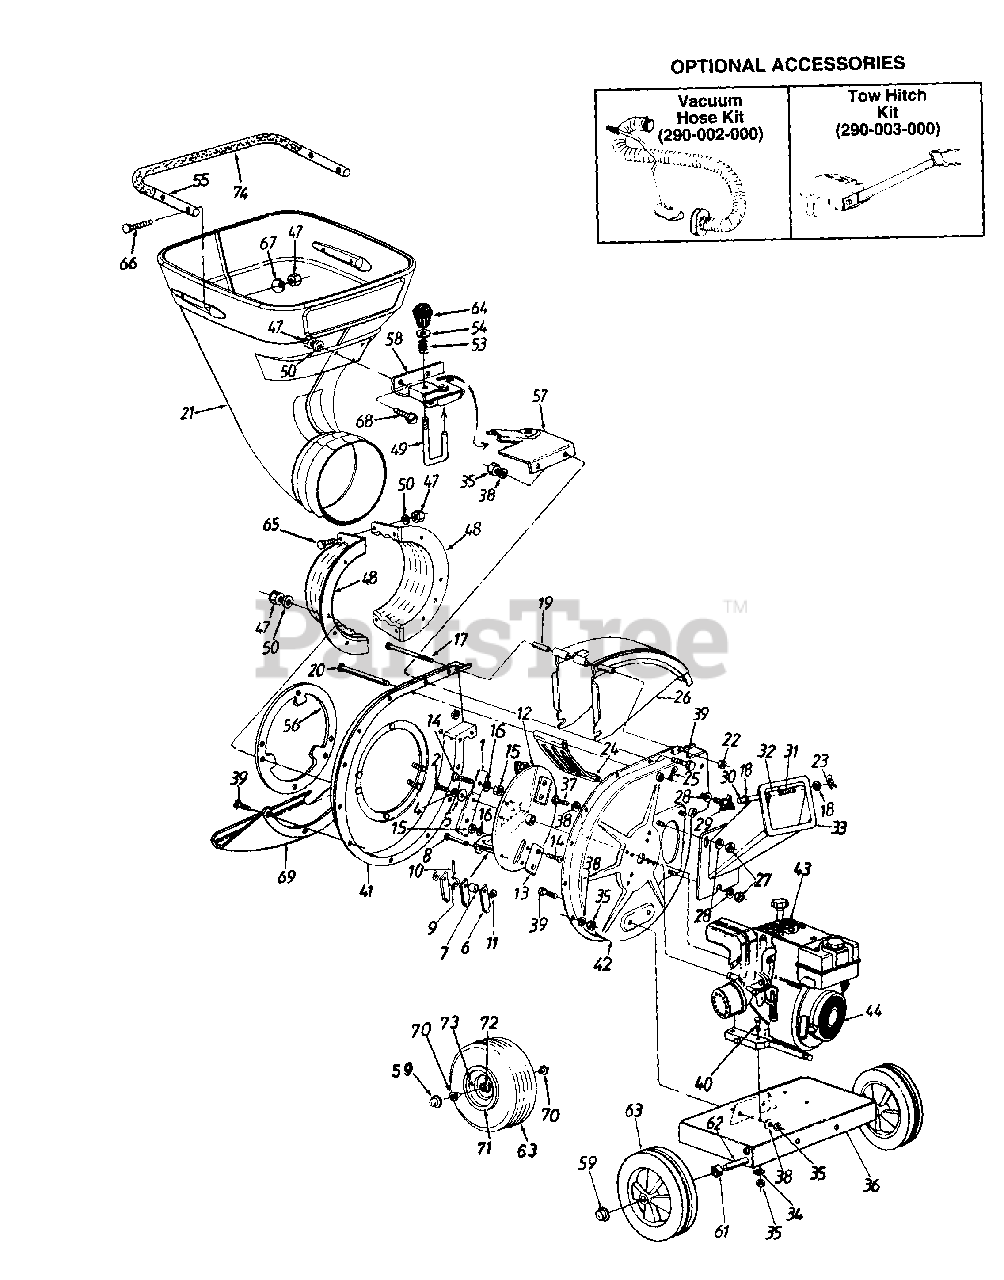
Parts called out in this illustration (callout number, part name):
1	Blade
2	Hex Patch Bolt 3/8-24 x 2.25" Lg.
4	L-Wash. 3/8" I.D. H.D.
5	Fl-Wash .406" I.D. x 1.25" O.D. Hdn.
6	Flail
7	Flail Spacer
8	Clevis Pin .496" Dia.
9	Flail Spacer w/.160" Dia. Hole
10	Spring Roll Pin 1.125" Lg.
11	Fl-Wash .531" I.D. x .94" O.D.
12	Impeller Ass'y. Comp.
13	Chipper Blade
14	Flat Hd. Scr. 5/16-24 x .75" Lg.
15	Hex Top L-Nut 5/16-24 (Gr. 5)
16	L-Wash. 5/16" I.D.
17	Hex Bolt 1/4-20 x 3.75" Lg.
18	Fl-Wash .281" I.D. x .50" O.D.
19	Chute Hinge Spacer 1.66" Lg.
20	Clevis Pin .5" Dia. x 4.62" Lg.
21	Rotating Hopper
22	Hex Ctr. L-Nut 1/4-20 Thd.
23	Cotter Pin
25	Internal Cotter Pin 3/8" Dia.
27	Hex Nut 5/16-18 Thd. (Gr. 5)
28	Bell-Wash .345" I.D. x .88"
29	Hand Knob
30	Chipper Door Rod
31	Torsion Spring 1.14" Lg.
35	Hex Nut 5/16-18 Thd. (Gr. 5)
37	Hex Bolt 5/16-24 x .75" Lg.
38	L-Wash. 5/16" I.D.
39	Hex Bolt 5/16-18 x .75" Lg. (Gr. 5)
40	Hex Bolt 5/16-18 x 1.5" Lg.
44	Engine
47	Elastic Lock Nut 5/16-18 Thd.
48	Hopper Mtg. Collar
49	Locking Pin
50	Fl-Wash. 5/16" I.D.
53	Spring 1.5" Lg.
54	Fl-Wash .385" I.D. x .62" O.D.
61	Spacer .64" I.D. x .38" Lg.
62	Shredder Axle
63	Wheel Ass'y. Comp.
64	Knob
65	Hex Bolt 5/16-18 x 1" Lg. (Gr. 5)
66	Curved Carr. Bolt 5/16-18 x 1.25" Lg.
67	Saddle Wash .32" I.D.
68	Carr. Bolt 5/16-18 x .75" Lg.
70	Flange Bearing.632" I.D.
73	Air Valve
74	Foam Grip
